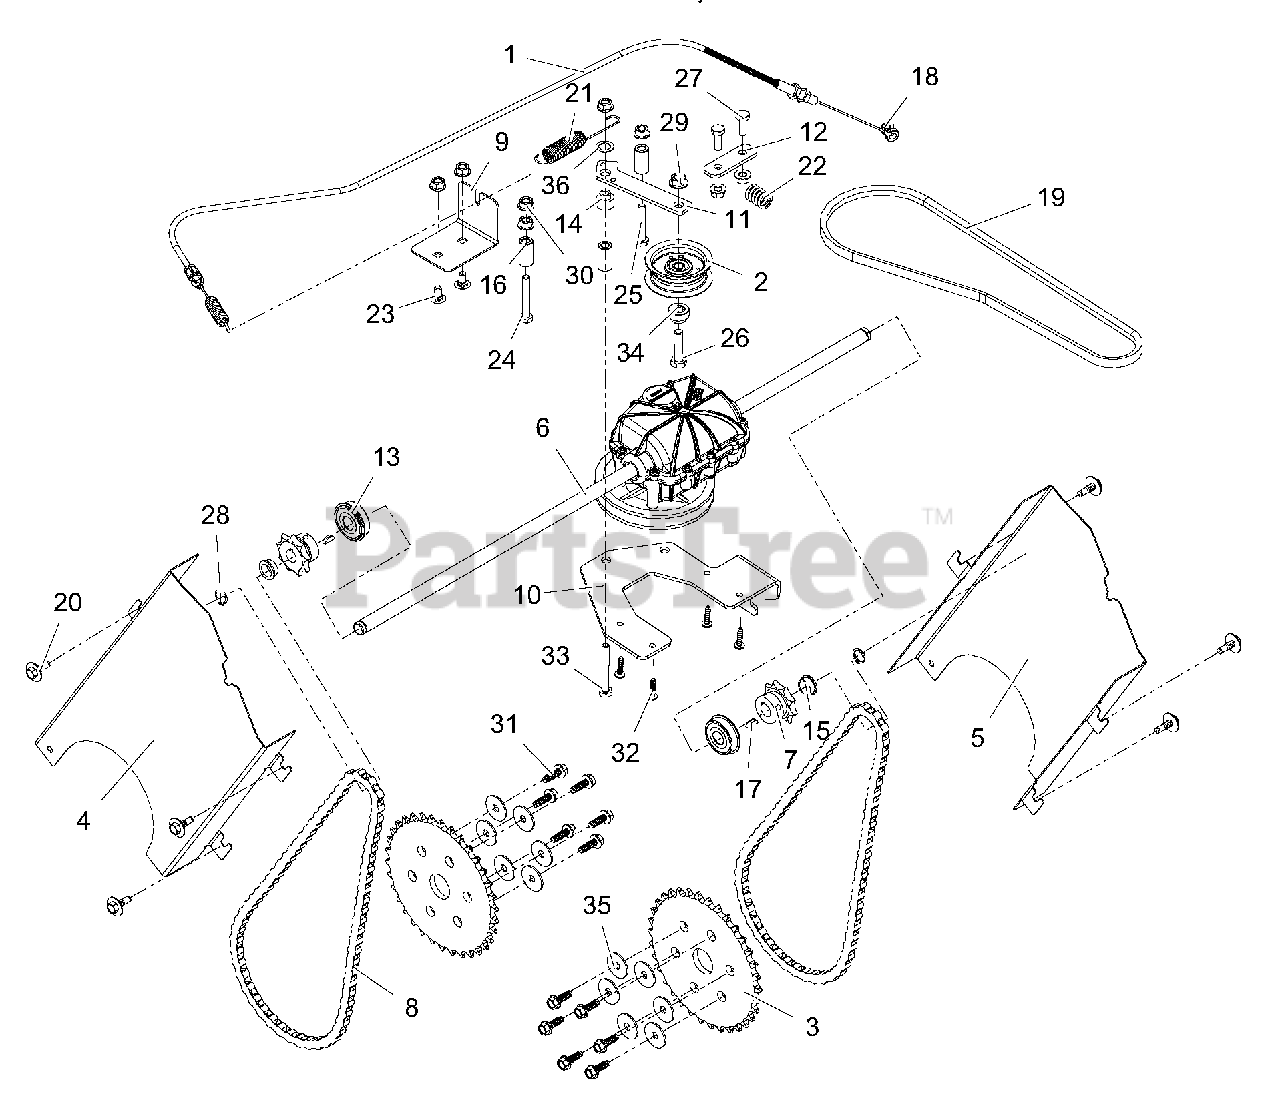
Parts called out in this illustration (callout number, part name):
1	CABLE, TRACTION
2	IDLER, FLAT - 2.00"
3	SPROCKET, DRIVE - 41 34T FLAT
4	GUARD, CHAIN - RIGHT APV
5	GUARD, CHAIN - LEFT APV
6	TRANS, DRIVE -GT MA502
7	SPROCKET, DRIVE - 41 9T #404KW
8	CHAIN, ROLLER - #41 64 PITCHES
9	MOUNT, CABLE - APV TRACTION
10	MOUNT, TRANS - APV
11	ARM, IDLER - APV BELT DRIVE
12	PLATE, RETAINER - APV TRANS
13	BRG, BALL .501 x 1.38 x .438 SEALED
14	BSHG, FLANGE .263 x .394 x .625 x .528
15	BSHG, FLANGE .500 x .625 x .270 x .750
16	BSHG, SLV .265 x .505 x .995
17	KEY, WDRF .125 x .50 x .20 (HRDEND)
18	NUT, PUSH .25 x .50 O.D.
19	V-BELT, 3LWRAPPED CLUTCHING (NO RUBBER BLEED THRU)
20	SCR, TAP .25-20 x .5 CAPTIVE
21	SPRG, EXTENSION
22	SPRG, COMPRESSION
23	BLT-RDHDSQNK .25-20 x .50 G5 Y
24	BLT-HEX .25-20 x 1.75 GR5 YWZC
25	BLT-HEX .25-20 x 1.50 GR5 YWZC
26	BLT-HEX .31-18 x 1.25 GR5 YWZC
27	BLT-HEX .25-20 x .75 GR5 YWZC
28	RG-RTNG-EXT .500 x .050
29	NUT, LK-TOP-FLG .312-18 YWZC
30	NUT, LK-TOP-FLG .25-20 YWZC
31	SCR-HEX .25-14 x .75 YWZC
32	SCR-TAP #10-14 x .75 PLASTITE BLZC
33	BLT-HEX .25-20 x 2.00 GR5 YWZC
34	BSHG, FLG .315 x .500 x .481 x .281
35	WSHR-FL-STL .281 x 1.000 x .063 YWZC
36	WSHR, - FIBER .437 x .656 x .032
